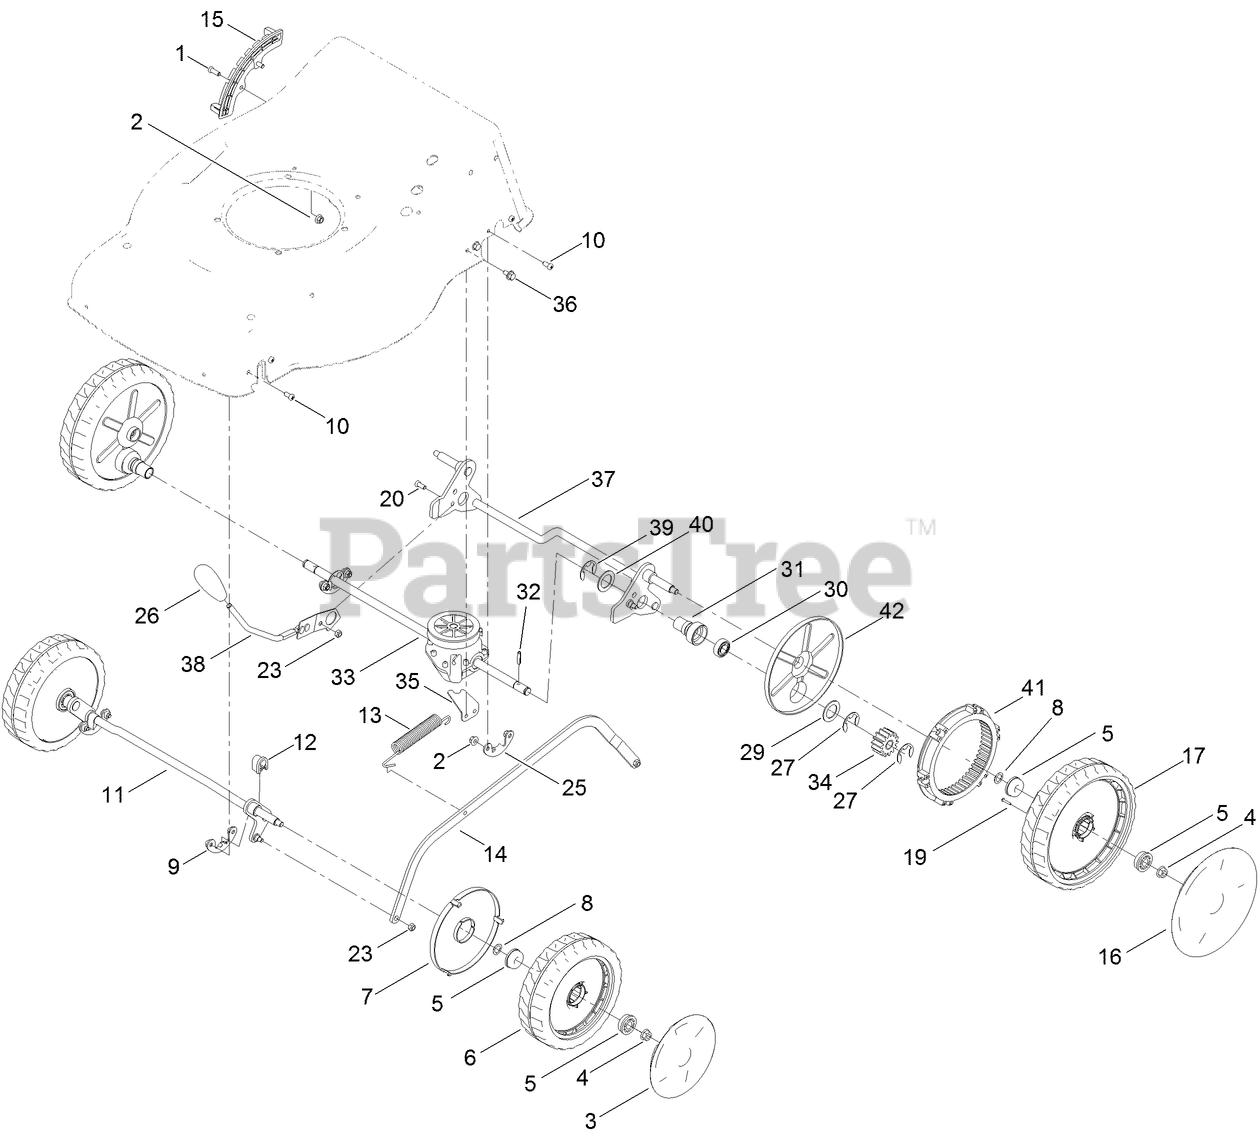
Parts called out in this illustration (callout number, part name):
1	SCREW-TOOTH
2	NUT-LOCK, FLANGE
3	CAP-HUB (7)
4	NUT-LOCK, FLANGE
5	BEARING
6	WHEEL ASM (7)
7	COVER-WHEEL, DUSTPROOF
8	WASHER-WAVE
9	CLAMP-AXLE, FIXED
10	SCREW-TOOTH
11	FRONT WHEEL AXIS ASM
12	RING-FIXED
13	SPRING-TENSION
14	BRACKET-CONNECTING, HOC
15	BOARD-ADJUSTER, HOC
16	CAP-HUB (8)
17	WHEEL ASM (8)
19	SCREW-SELF DRIVING
20	SCREW-PAN, CROSS
23	NUT-LOCK
25	RING-FIXED
26	HANDLE-LEVER, HOC
27	WASHER-SPRING
29	WASHER-FLAT
30	BEARING
31	SHEATH-BEARING
32	PIN-CYNLINDRICAL
33	GEARBOX
34	GEAR OUTPUT ASM-LH
35	BRACKET-LOCATION
36	BOLT-HH, FLANGE
37	REAR AXLE SHAFT ASM
38	HANDLE ASM
39	WASHER-SPRING
40	WASHER
41	GEAR RING
42	COVER-WHEEL, DUSTPROOF
